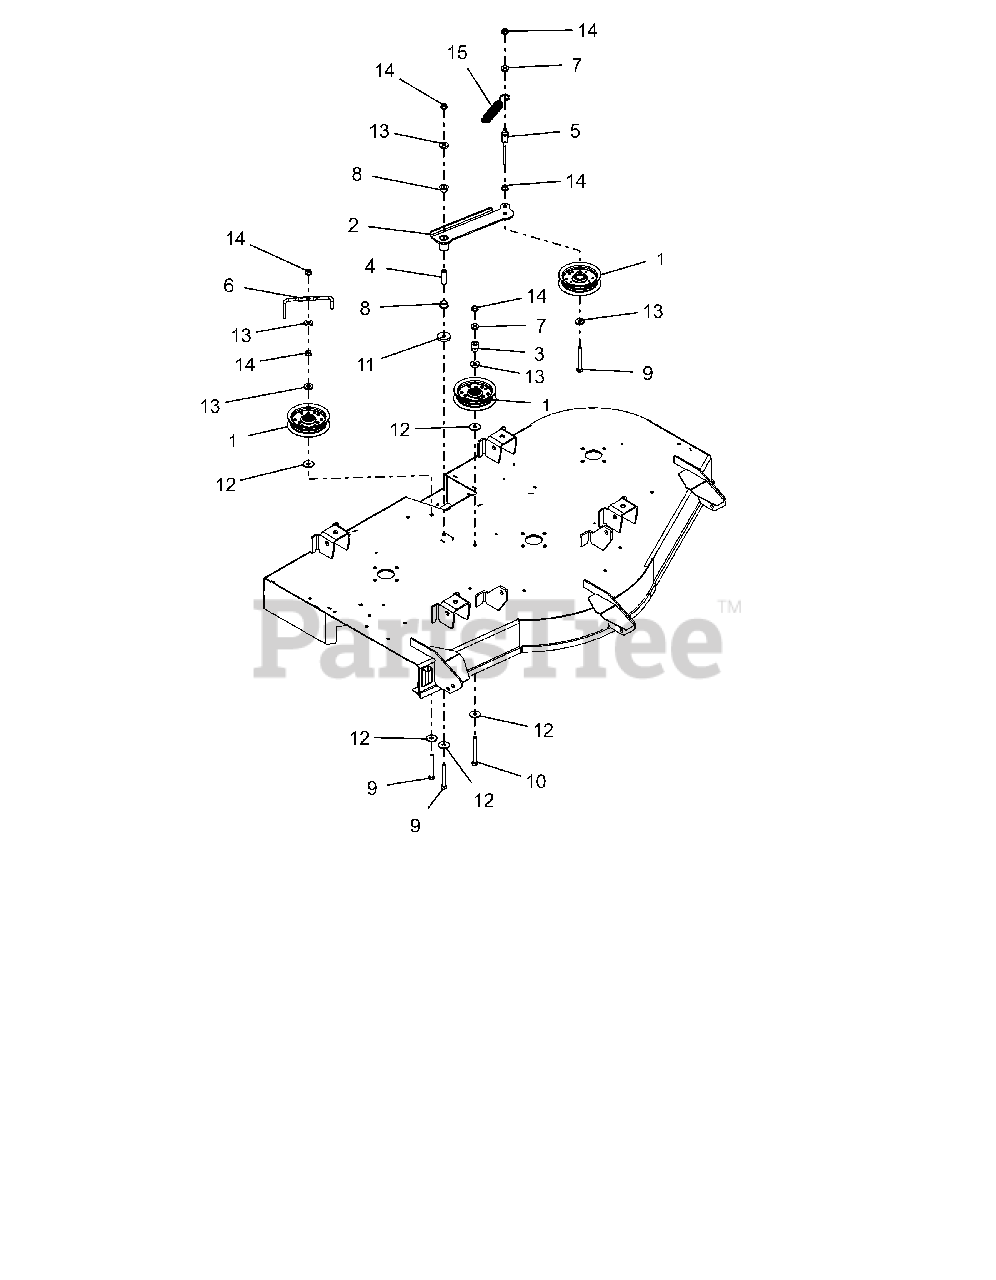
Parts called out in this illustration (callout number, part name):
1	ASM, IDLER 4"
2	WLDMT, IDLER ARM-52"
3	BUSHING, IDLER (P/M)
4	SPACER, .375IDX.625ODX1.66 PM
5	WIREFORM, BELT FINGER
6	WIREFORM, BELT FINGER
7	BSHG-FLG .385X.500X.875X.406
8	BSHG-FLG, .625X.750X.500X1.00
9	BLT, HEX .38-16X3.00F G5 ZCC
10	BLT, HEX .38-16X3.50 G5 ZCC
11	WSHR, FLT .406X1.50X.245 ZCC
12	WSHR FL STL .406X1.25X.10ZC120
13	WSHR, FLT .406X1.00X.188 ZCC
14	NUT-LK-TOP-FLG .38-16 ZC120
15	SG-TENS .135X.98X6.0 WLD 62
